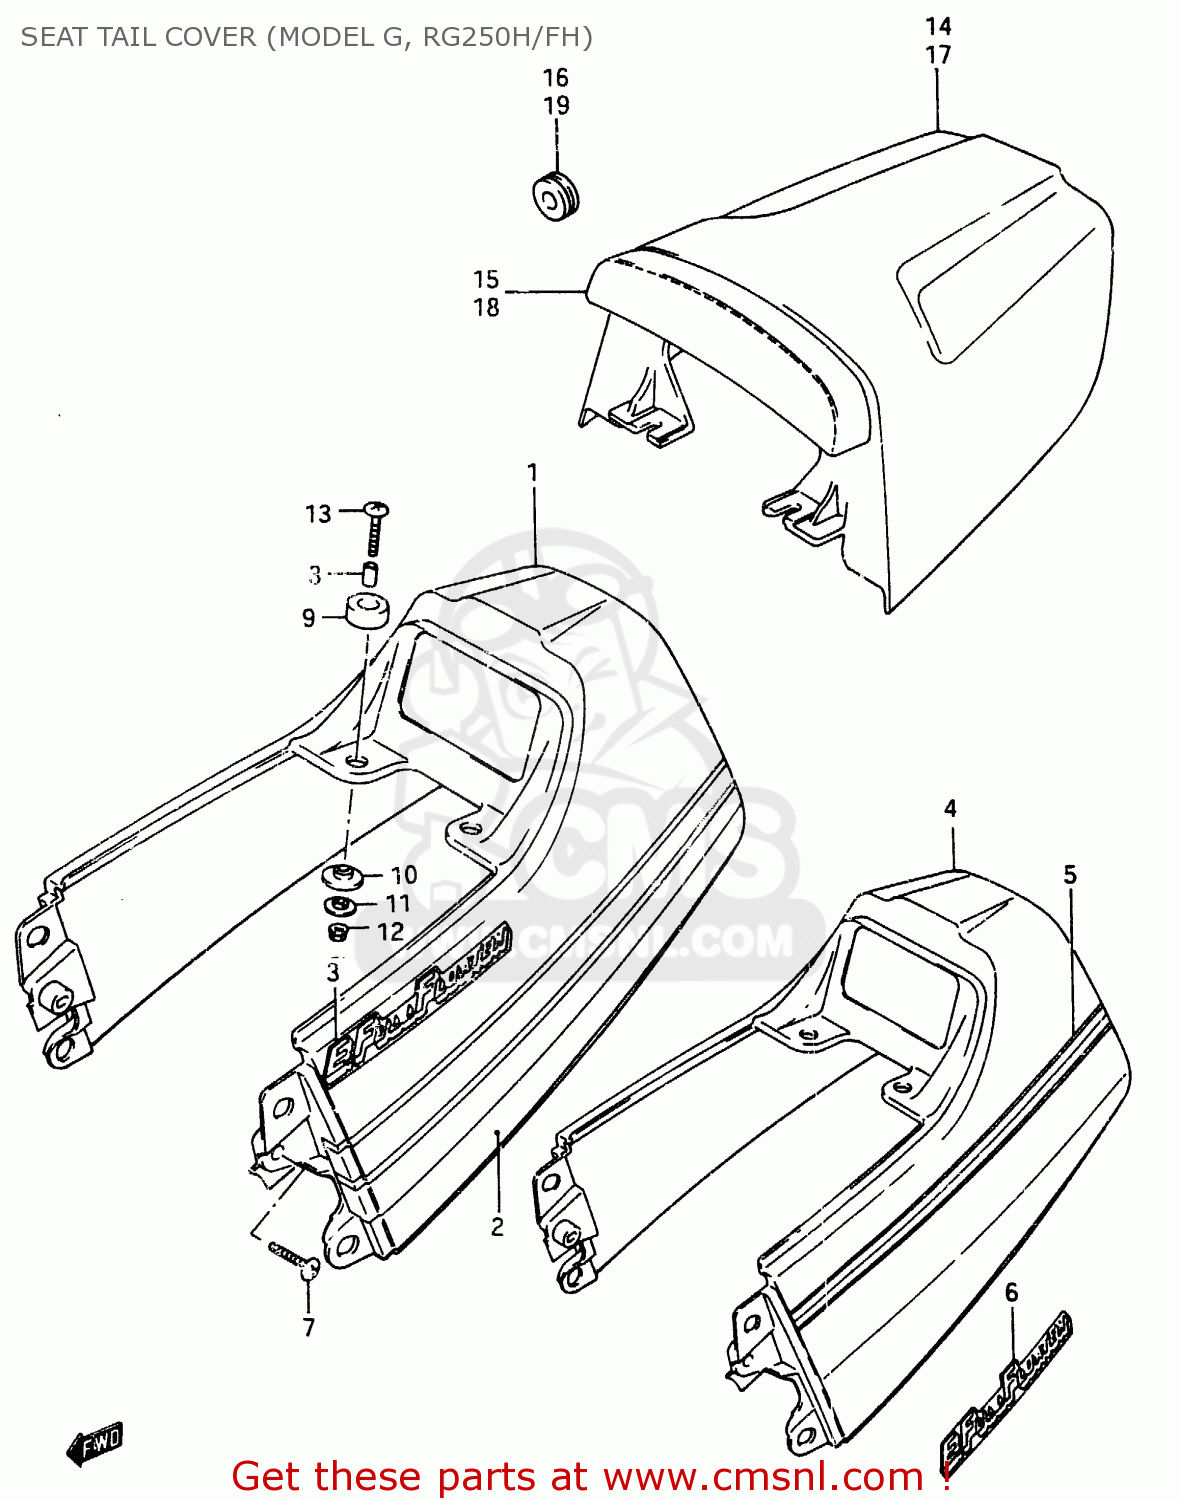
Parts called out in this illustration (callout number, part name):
1	COVER, SEAT TAIL (RED)
2	TAPE SET, SEAT TAIL COVER
3	EMBLEM
4	COVER, SEAT TAIL
5	TAPE SET, TAIL COVER
6	EMBLEM
7	SCREW
8	SPACER (6.1X8X12)
9	CUSHION,COVER
10	CUSHION,SEAT TAIL COVER LWR
11	WASHER
12	NUT
13	SCREW
14	BOX SET, SEAT TAIL (RED)
15	BACKREST, SEAT (BLUE)
16	CUSHION
17	BOX SET, SEAT TAIL (BLUE)
18	BACKREST, SEAT (BLUE)
19	CUSHION
